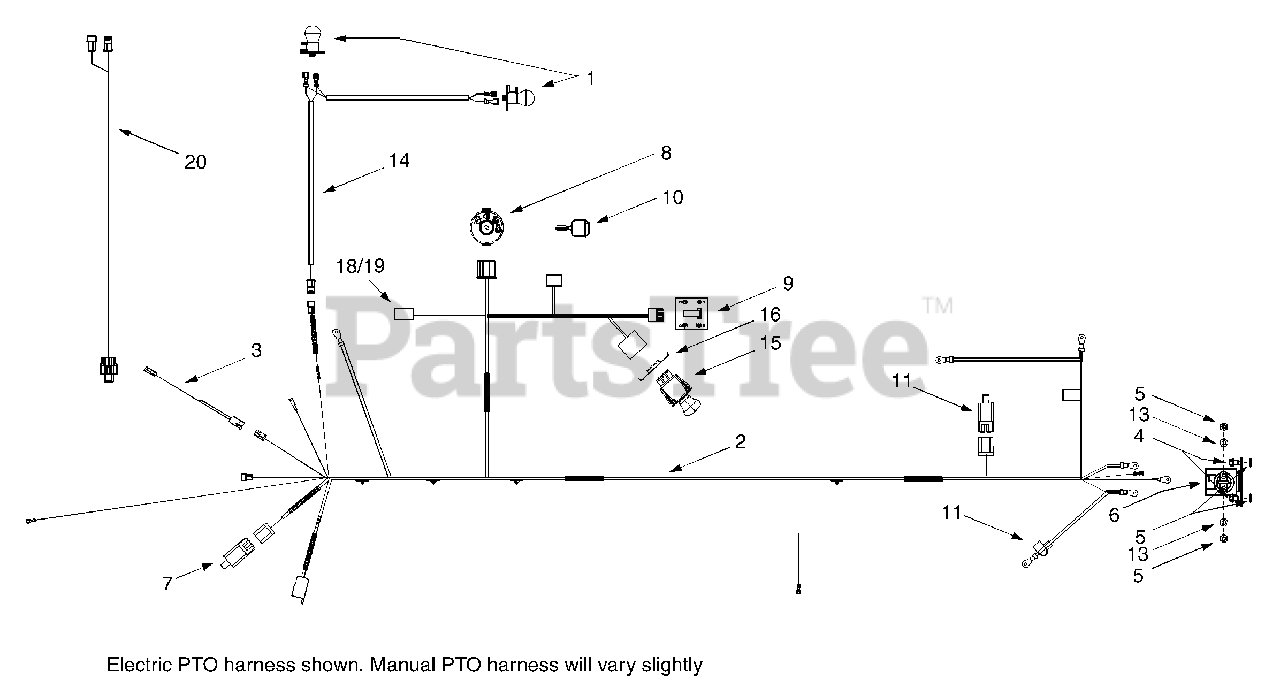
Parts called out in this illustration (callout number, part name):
1	Bulb/Socket Headlight Assembly
2	Wiring Harness w/o Ref. 14
3	Harness Adapter, #18 x 5
4	Self Tapping Screw, 1/4-20 x .5
5	Hex Nut, 1/4-20
6	Solenoid, 12-volt, 100 Amp
7	Snap Mount Safety Interlock Switch (Brake)
8	Ignition Switch
9	Indicator Monitor / Hour Meter
10	Ignition Key
11	Safety Plunger Switch (Seat)
13	Lock Washer, 1/4
14	Headlight Harness
15	Electric PTO Switch
16	Retainer Bracket
18	Fuse Holder
19	20-amp Fuse
20	Harness Adapter
